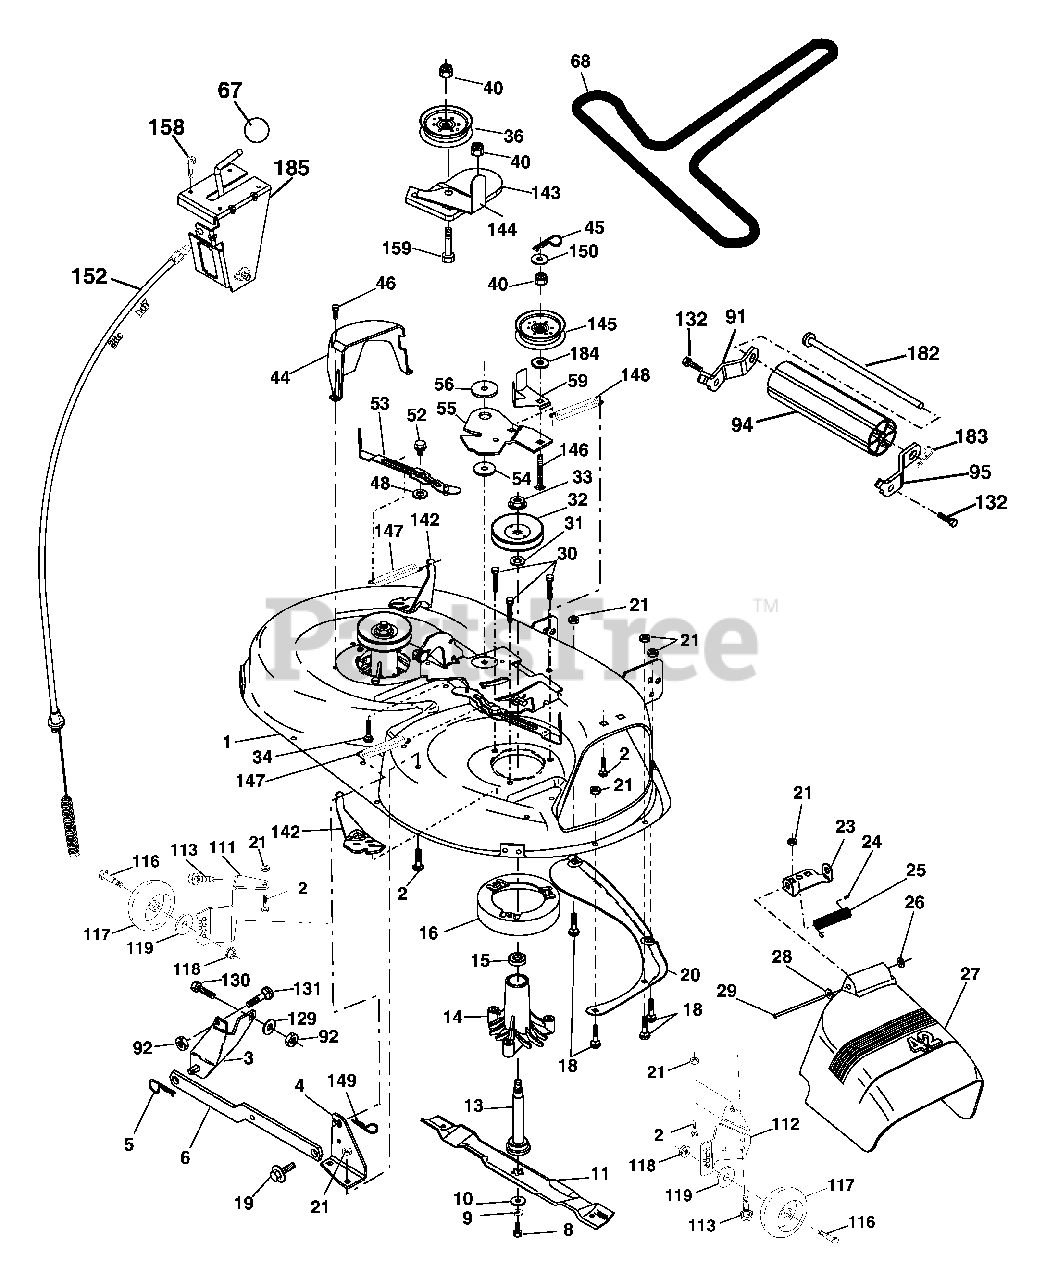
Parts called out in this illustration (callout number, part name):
1	Mower Deck Assembly, 42"
2	Bolt
3	Bracket Asm Fr. Sway Bar 3/42
4	Bracket Asm Deck 42" Sway Bar
5	Retainer Spring
6	Bar Sway Deck
8	Bolt 3/8-24 x 1.25 Gr. 8 patched
9	Washer, Lock
10	Washer, Hardened
11	Blade Mower 42" Hi-Lift
11	Blade, Mulching 42" Std
11	Blade Mulching 42" Premium
13	Shaft Assembly, Mandrel, Vented
14	Housing, Mandrel, Vented
15	Bearing, Ball, Mandrel
16	Stripper, Mandrel Deck
18	Bolt, Carriage 5/16-18 x 5/8
19	Bolt, Shoulder
20	Baffle, Vortex
21	Nut
23	Bracket, Deflector Mower 42"
24	Cap, Sleeve 80 x 112 Blk Mower
25	Spring, Torsion, Deflector 2 52
26	Nut, Push Phos & Oil
27	Shield, Deflector 42" Blk
28	Washer 11/32 x 5/8 x 16 Ga.
29	Rod, Hinge 42" 6 75 W/G
30	Screw Thdrol
31	Washer, Spacer Mower Vented
32	Pulley, Mandrel
33	Nut, Toplock
34	Bolt Carr SH 3/8-16 x 1-1/2 Gr.5
36	Pulley, Idler, Flat
40	Nut Lock 3/8-16
44	Guard, Mandrel, LH
45	Retainer
46	Screw, Thdrol 1/4-20 x 5/8 T
48	Washer, Hardened
52	Bolt, Shoulder 5/16-18 unc
53	Arm Assembly, Pad, Brake
54	Washer, Hardened
55	Arm, Idler
56	Spacer, Retainer
59	Guard TUV Idler
67	Knob Round
68	V-Belt, 42" Mower
91	Bracket Asm LH
92	Nut Lock Hex 3/8-16 unc
94	Roller Nose
95	Bracket Nose RH
111	Bracket Wheel Guage LH
112	Bracket Wheel Guage RH
113	Screw 5/16-18
116	Bolt, Shoulder
117	Wheel, Gauge
118	Nut Centerlock 3/8-16
119	Washer 3/8 x 7/8 x 14 Ga.
129	Washer 13/32 x 13/16 x 12 Ga.
130	Bolt Fin Hex 3/8-16 x 1
131	Bolt Rdhd Sqnk 3/8-16 x 1
132	Screw 3/8-16 x 3/4
142	Arm Spring Brake Mower
143	Bracket Arm Idler 42"
144	Keeper Belt 42" Clutch Cable
145	Pulley Idler Flat
146	Bolt Carriage Idler
147	Spring Extension
148	Spring Return Idler
149	Retainer Spring Yellow
150	Washer 9/32 x 3/4 x 10 Ga.
152	Clutch Cable 42"
158	Screw Hex Thd Cut 1/4-20 x 1/2
159	Bolt Rdhd Sqn 3/8-16 unc x 1-3/4
182	Rod Roller Nose
183	Retainer Clip
184	Washer 13/32 x 7/8 x 10 Ga.
185	Head Asm Cable Clutch
